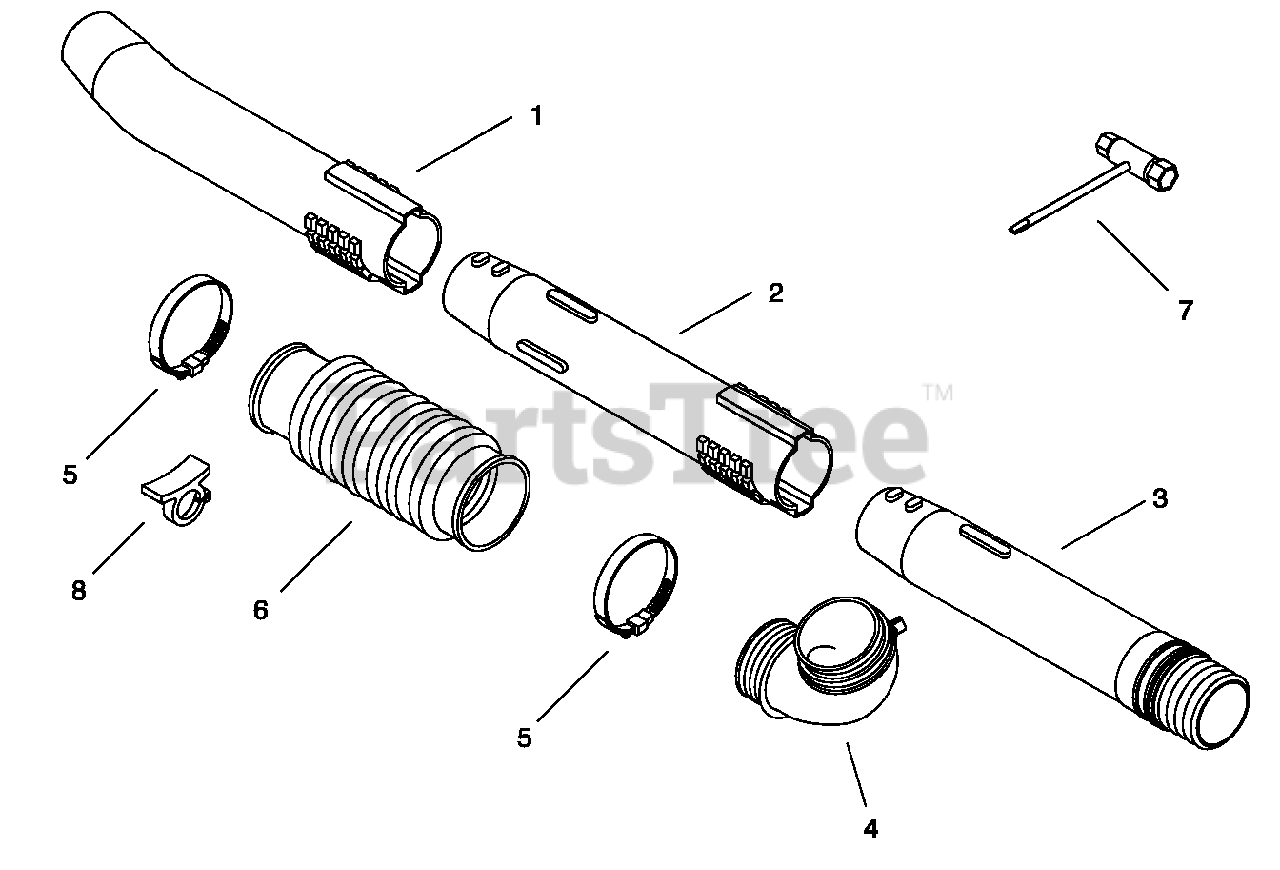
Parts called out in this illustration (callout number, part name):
1	TUBE, BLOWER - STRAIGHT NOZZLE
2	TUBE, BLOWER - STRAIGHT
3	TUBE, BLOWER - SWIVEL
4	TUBE, BLOWER - ELBOW
5	CLAMP, HOSE
6	TUBE, BLOWER - FLEXIBLE
7	T-WRENCH - 10X19mm
8	CLIP, CABLE
